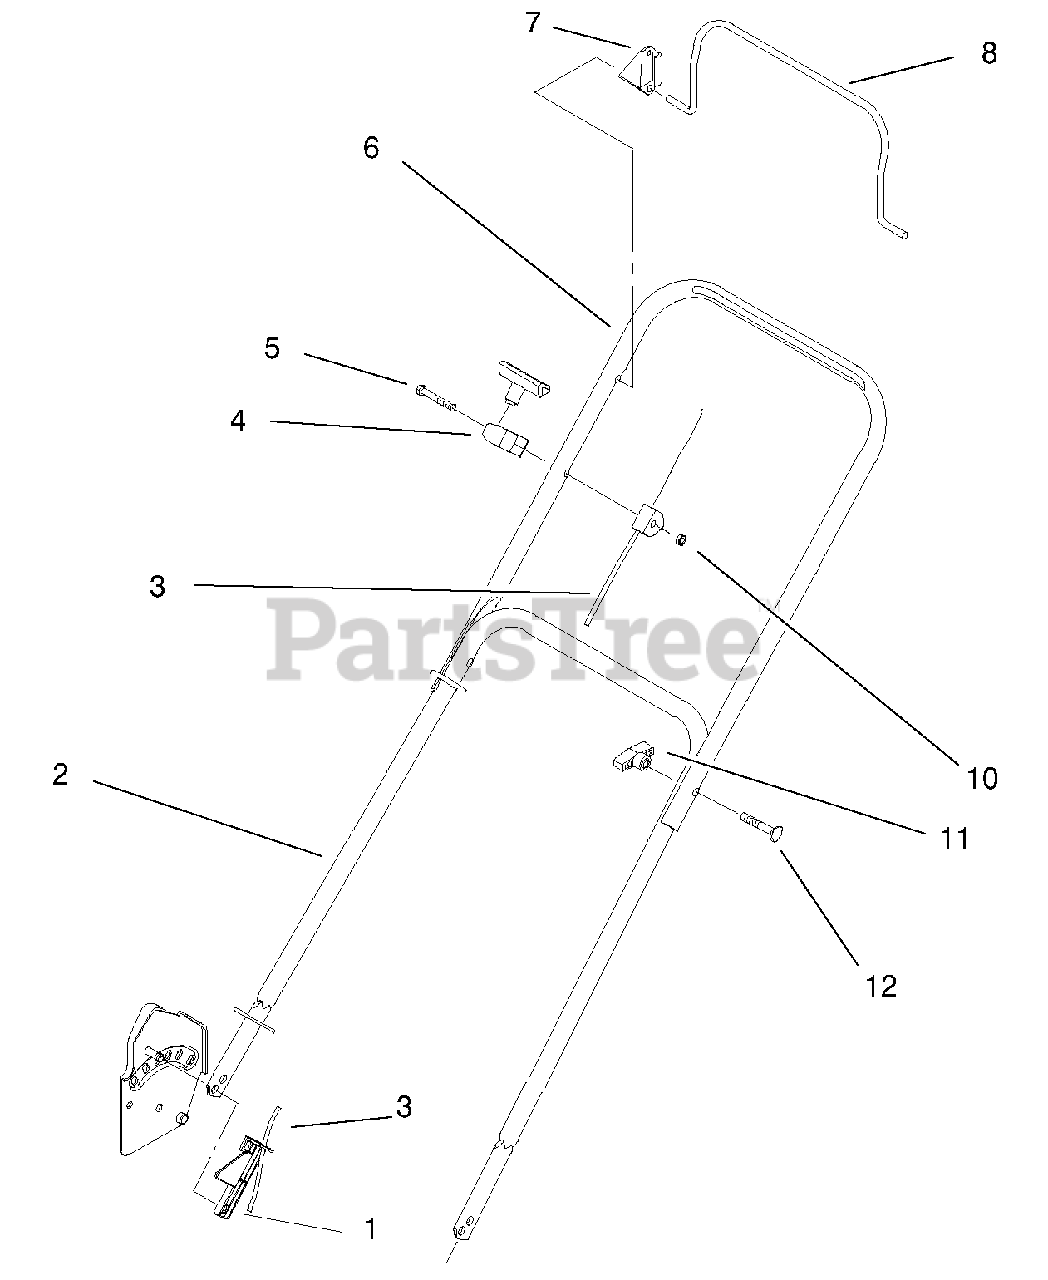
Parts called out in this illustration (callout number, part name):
1	GUARD-CABLE
2	HANDLE - LOWER
3	BRAKE CABLE ASM
4	GUIDE-ROPE
5	SCREW-HH
6	HANDLE-UPPER
7	STOP-PIVOT
8	BAIL - BRAKE
10	NUT-LOCK, NI
11	KNOB-HANDLE
